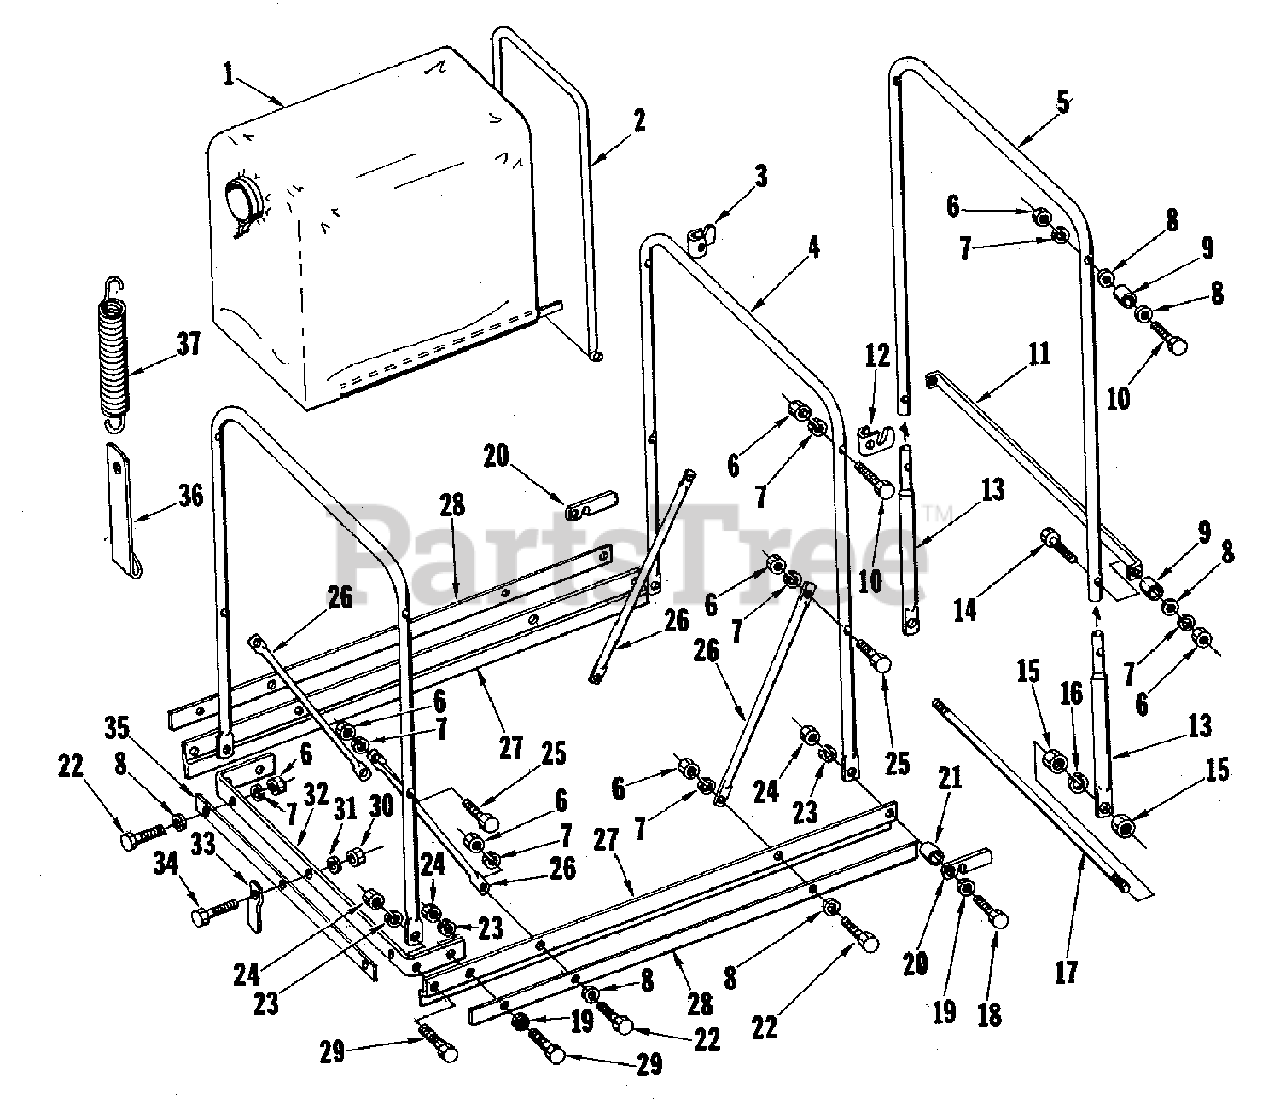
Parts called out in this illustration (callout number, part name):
3	CATCH, Door, (R.H.)
4	UPRIGHT, Front, Rear
5	DOOR, Rear, Top
6	NUT, Hex, 1/4-20
7	WASHER, Lock, 1/4
8	WASHER, Flat, 1/4
10	SCREW, Cap, 1/4-20 x 1-1/2
11	BAR, Door, Rear
12	CATCH, Door (L.H.)
13	TUB E, Door, Rear
14	SCREW, Cap, 1/4-20 x 1-3/4
15	NUT, Hex, 1/2-13
16	WASHER, Lock, 1/2
17	ROD, Door, Rear
18	SCREW, Cap, 5/16-18 x 7/8
19	WASHER, Flat, 5/16
20	LATCH, Rear Door
22	SCREW, Cap, 1/4-20 x 3/4
23	WASHER, Lock, 5/16"
24	NUT, Hex, 5/16-18
25	SCREW, Cap, 1/4-20 x 1-1/4
26	TUBE, Crossbrace
28	STRIP, Hold Down, Side
29	SCREW, Cap, 5/16-18 x 1
30	NUT, Hex Lock, 3/8-16
31	WASHER, Flat, 3/8
34	SCREW, Cap, 3/8-16 x 1
35	STRIP, Hold Down, Front
